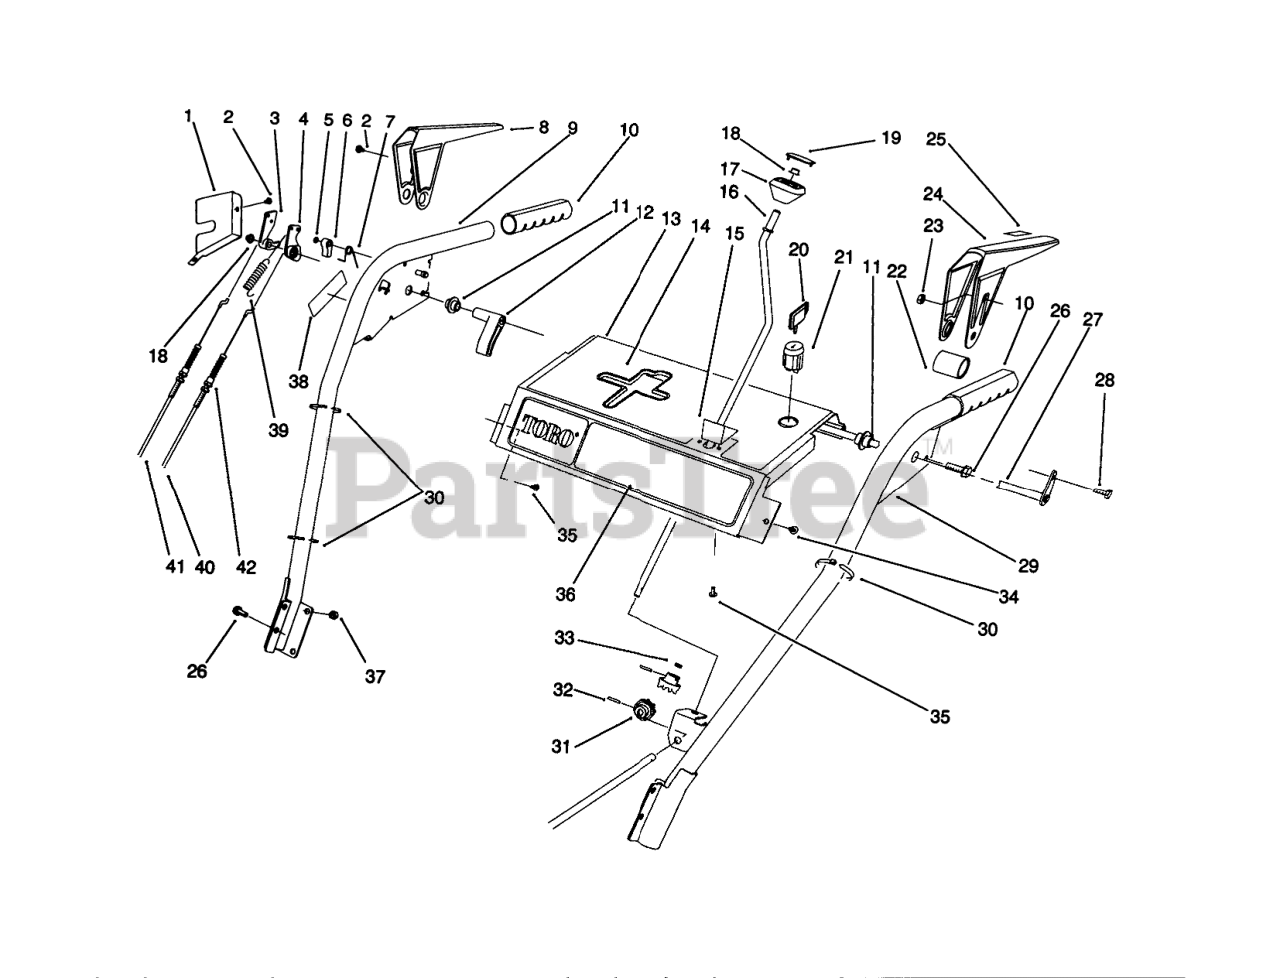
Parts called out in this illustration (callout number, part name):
1	Cover Lever Lock
2	SCREW-HH
3	TANG-LOCKING
4	CAM-RELEASE
5	E-RING-RETAINER
6	LATCH-LOCKING
7	SPRING-TORSION
8	Lever-Impeller
9	Handle-RH
10	GRIP-HANDLE
11	BUSHING-LEVER
12	LEVER-TRIP
13	Panel-Control
14	DECAL-TOP PANEL
15	PLATE-GUIDE
16	CRANK-ROD, CHUTE
17	KNOB-CONTROL, CHUTE
18	RETAINER-PUSH ON
19	COVER-KNOB
20	KEY-IGNITION
21	SWITCH
22	SPACER-LEVER, TRACTION
23	NUT-LOCK, NI
24	Lever-Traction
25	DECAL-LEVER
26	SCREW-HHF
27	CROSS ROD ASM
28	SCREW-HWH
29	Handle-LH
30	TIE-CABLE
31	GEAR-UNIVERSAL
32	PIN-SPRING
33	WASHER-RUBBER
34	SCREW-HWHTF
35	SCREW-PPH
36	DECAL-FRONT PANEL (824)
37	NUT-LOCK, NI
38	DECAL-WARNING
39	Spring-Extension
40	CABLE-TRACTION
41	CABLE-IMPELLER
42	NUT-LOCK, NI
